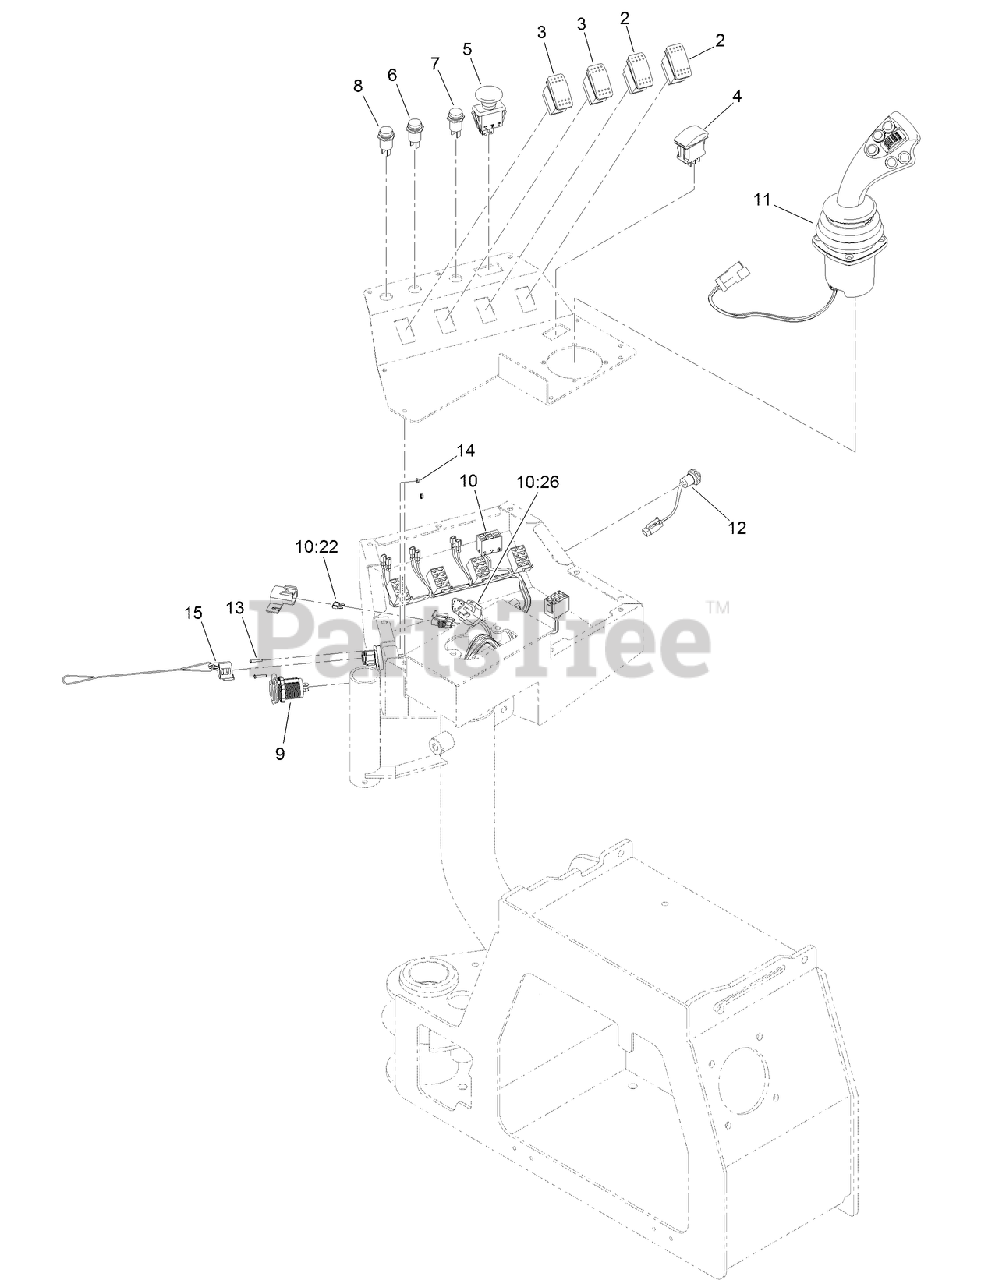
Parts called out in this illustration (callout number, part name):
2	SWITCH
3	SWITCH-INTERMITTENT
4	SWITCH
5	SWITCH, E-STOP
6	LAMP-INDICATOR, LED
7	LAMP-INDICATOR, LED
8	LAMP-INDICATOR, LED
9	SOCKET-USB
10	HARNESS-WIRE, LEFT CONSOLE
10:22	FUSE-MINI BLADE, 5 AMP
10:26	RESISTOR-120 OHM
11	JOYSTICK-LH
12	SWITCH-BUTTON, PUSH
13	SCREW-PPH
14	NUT-HEX, NYL INS
15	CAP/TETHER ASM
